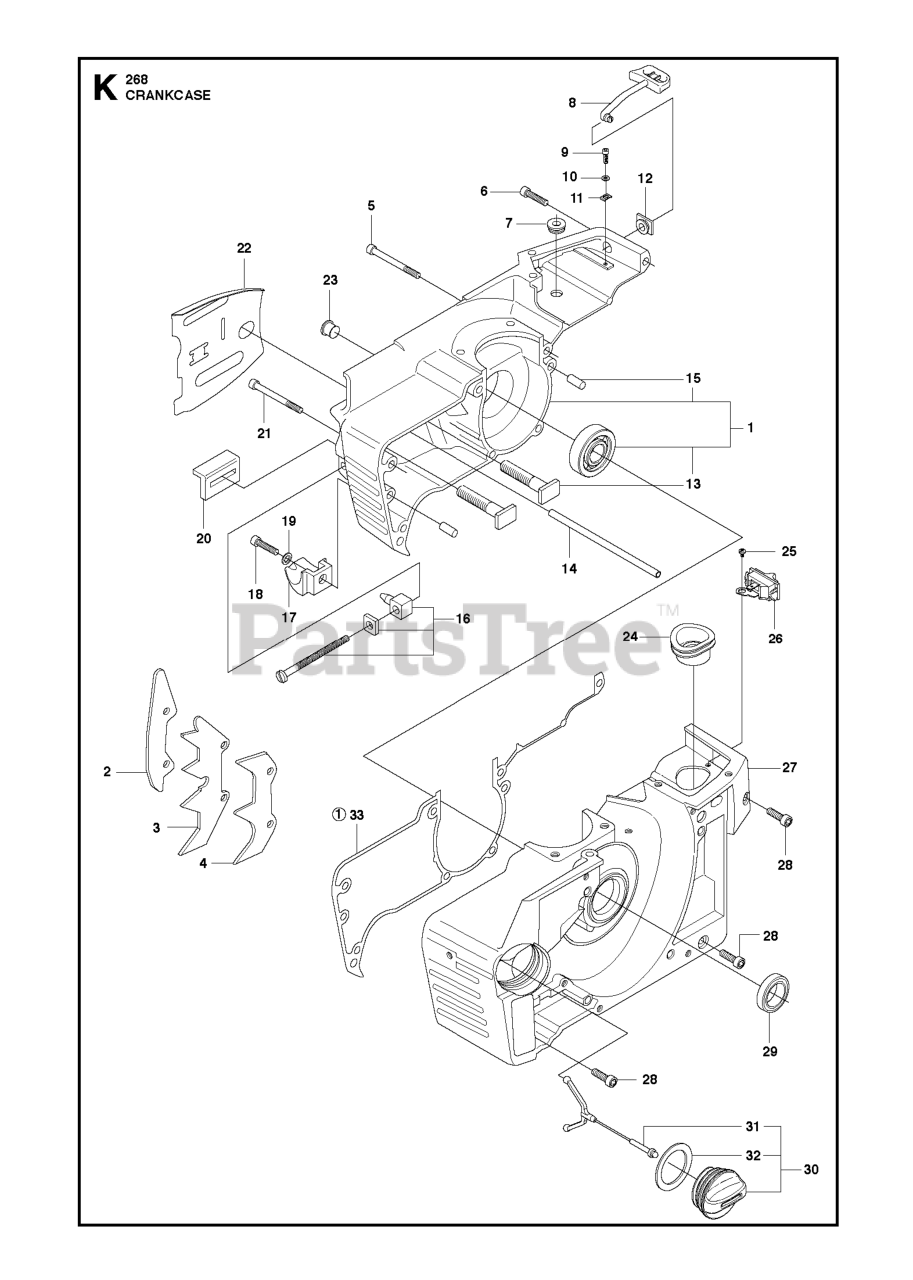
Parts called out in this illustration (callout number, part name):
1	CRANKCASE CPL
3	FELLING DOG
4	FELLING DOG
5	SCREW MC6S 5X35
6	SCREW MC6S 5X20
8	CHOKE CONTROL
9	SCREW MC6S 4X16
10	WASHER 4.2X9
14	OIL TANK VENT
15	PIN 5X14
16	CHAIN TENSIONER
17	CHAIN CATCHER
18	SCREW MC6S 5X12
20	CHAIN GUIDE
21	SCREW MC6S 5X50
22	PROTECTION PLATE
26	SWITCH ON/OFF
27	CRANKCASE CPL
28	SCREW MC6S 5X12
29	SEALING RING
32	OILCAP GASKET
33	GASKET SET
